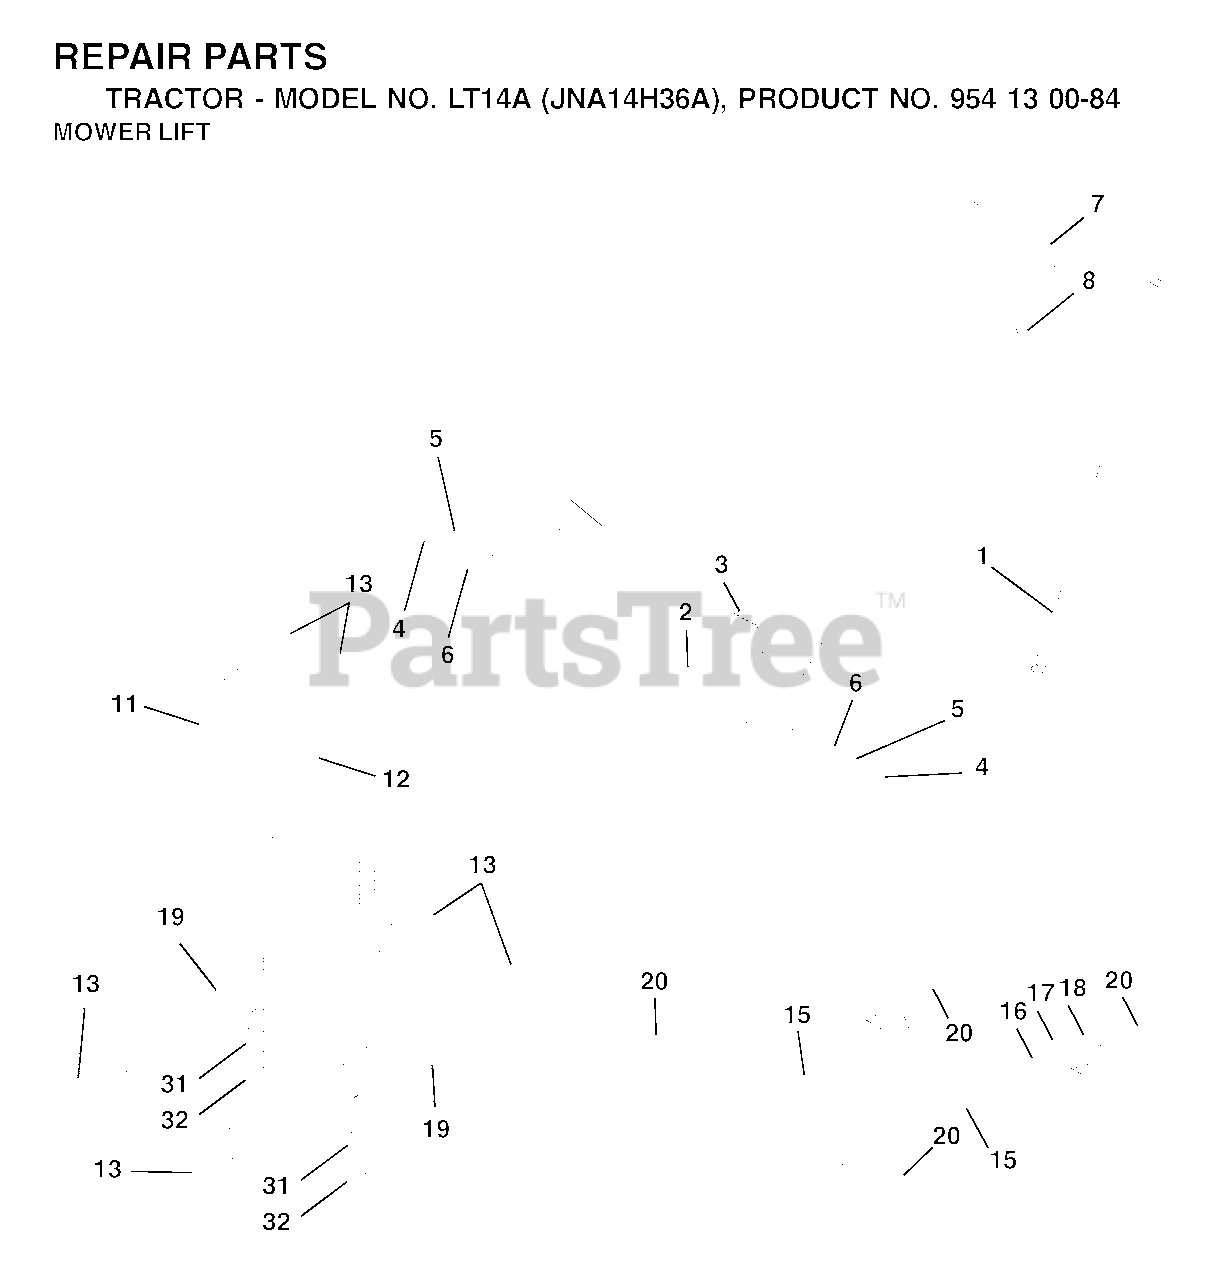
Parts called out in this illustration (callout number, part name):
1	WIRE ASM INNER W/ PLUNGER LT
2	SHAFT ASM R HANDLE
3	PIN GROOVE
4	RETAINING RING LT
6	BEARING.NYLON
7	GRIP
11	LINK LIFT LH
12	LINK LIFT RH
13	RETAINER-SPRNG RB
15	LINK.SUSPENSION.FRONT
16	NUT
18	NUT
19	ARM.REAR.SUSPENSION
20	SPRING RETAINER
31	BEARING.PIVOT.LIFT
32	NUT CROWNLOCK 3/8-24
